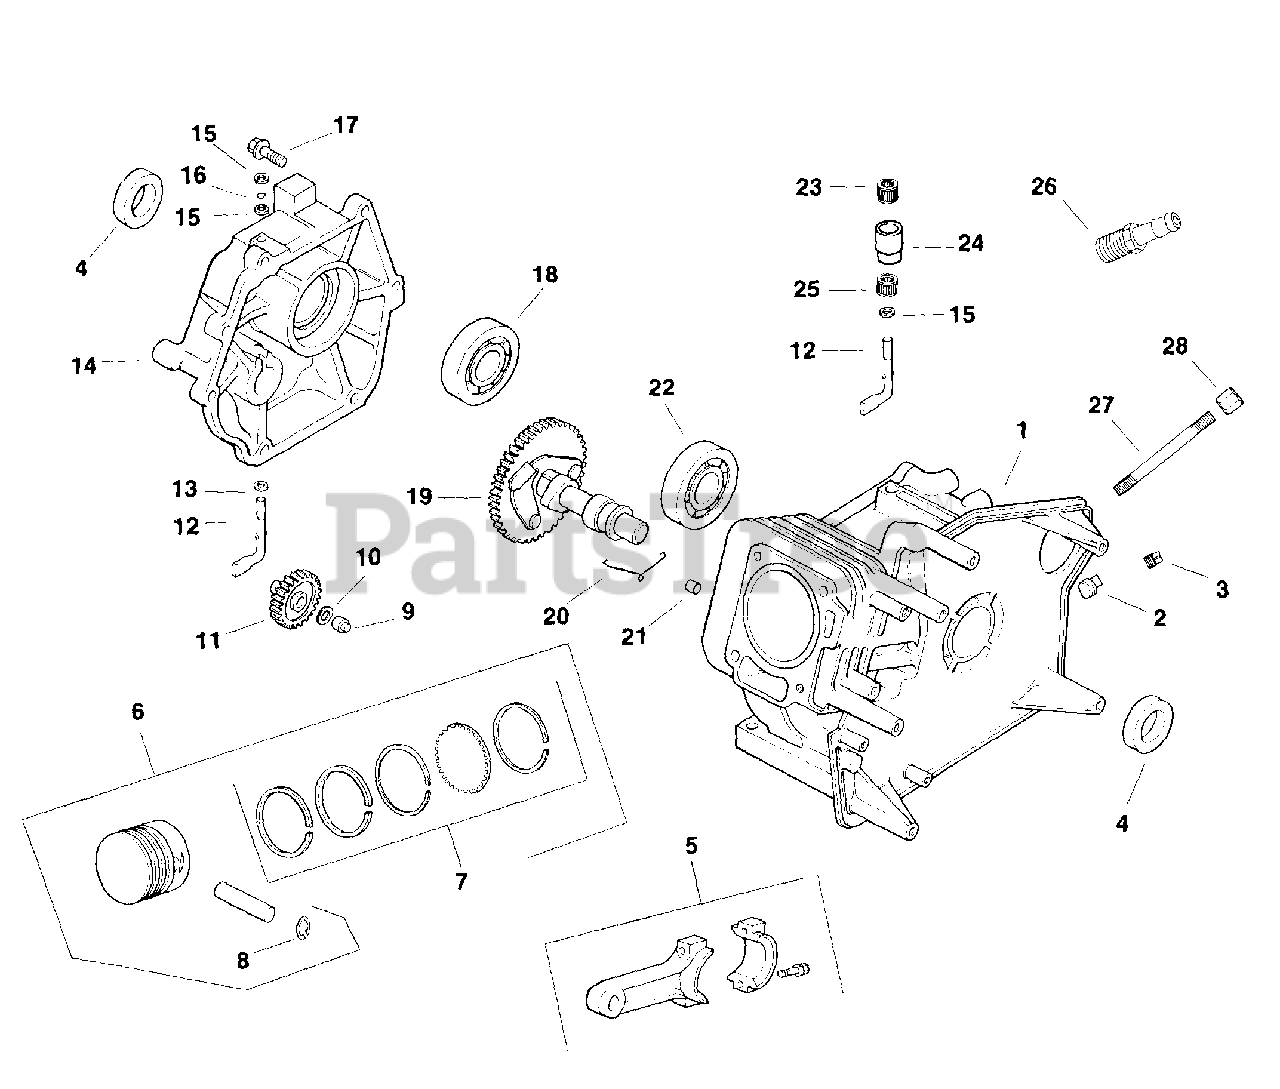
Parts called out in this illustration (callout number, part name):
1	Crankcase
2	PLUG,PIPE 1/2 NPTF SQUARE HD USE 25 139 61-S
4	SEAL - DISCONTINUED
5	ROD, CONNECTING STD - DISCONTINUED
5	ROD, CONNECTING .25-(#DSC)
6	KIT, PISTON W/RING SET STD.
6	PISTON W/RING SET .25
6	PISTON W/RING SET .50
7	RING SET STD. (KM)
7	RING SET .25MM
7	RING SET .50MM
8	RETAINER, PISTON
11	GEAR - USE 15 043 06
12	ARM, GOVERNOR
13	WASHER, FLAT 1/4"
14	PLATE, CLOSURE - DISCONTINUED
15	WASHER, FLAT 1/4" (O.D. 1/2")
17	Screw, closure plate M8x1.25x35.5
18	BEARING - DISCONTINUED
22	BEARING - DISCONTINUED
